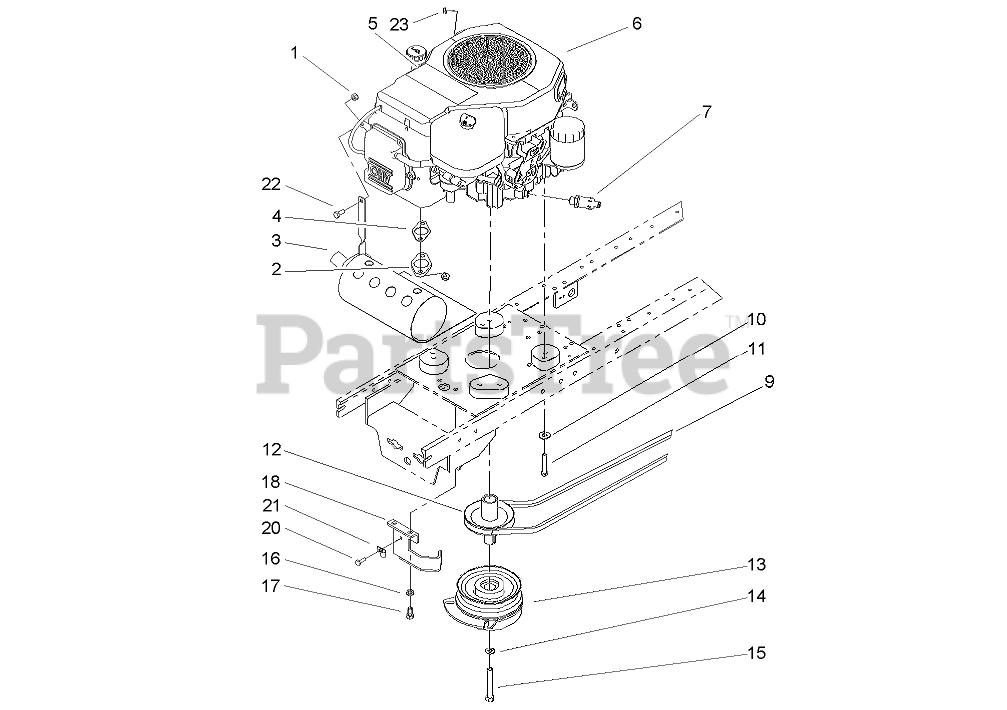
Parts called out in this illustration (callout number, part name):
1	NUT-LOCK, NI
2	NUT-HF
3	MUFFLER
4	Gasket-Exhaust
5	Decal-Power
7	VALVE-DRAIN, OIL
9	V-BELT, TRACTION
10	WASHER-LOCK
11	Screw-HH
12	PULLEY-ENGINE
13	CLUTCH
14	WASHER-FLAT
15	SCREW-HH
16	WASHER-LOCK
17	SCREW-HH
18	PTO STOP ASM
20	SCREW-HWH
21	CLAMP-R
22	SCREW-HH
23	NUT-KEPS
